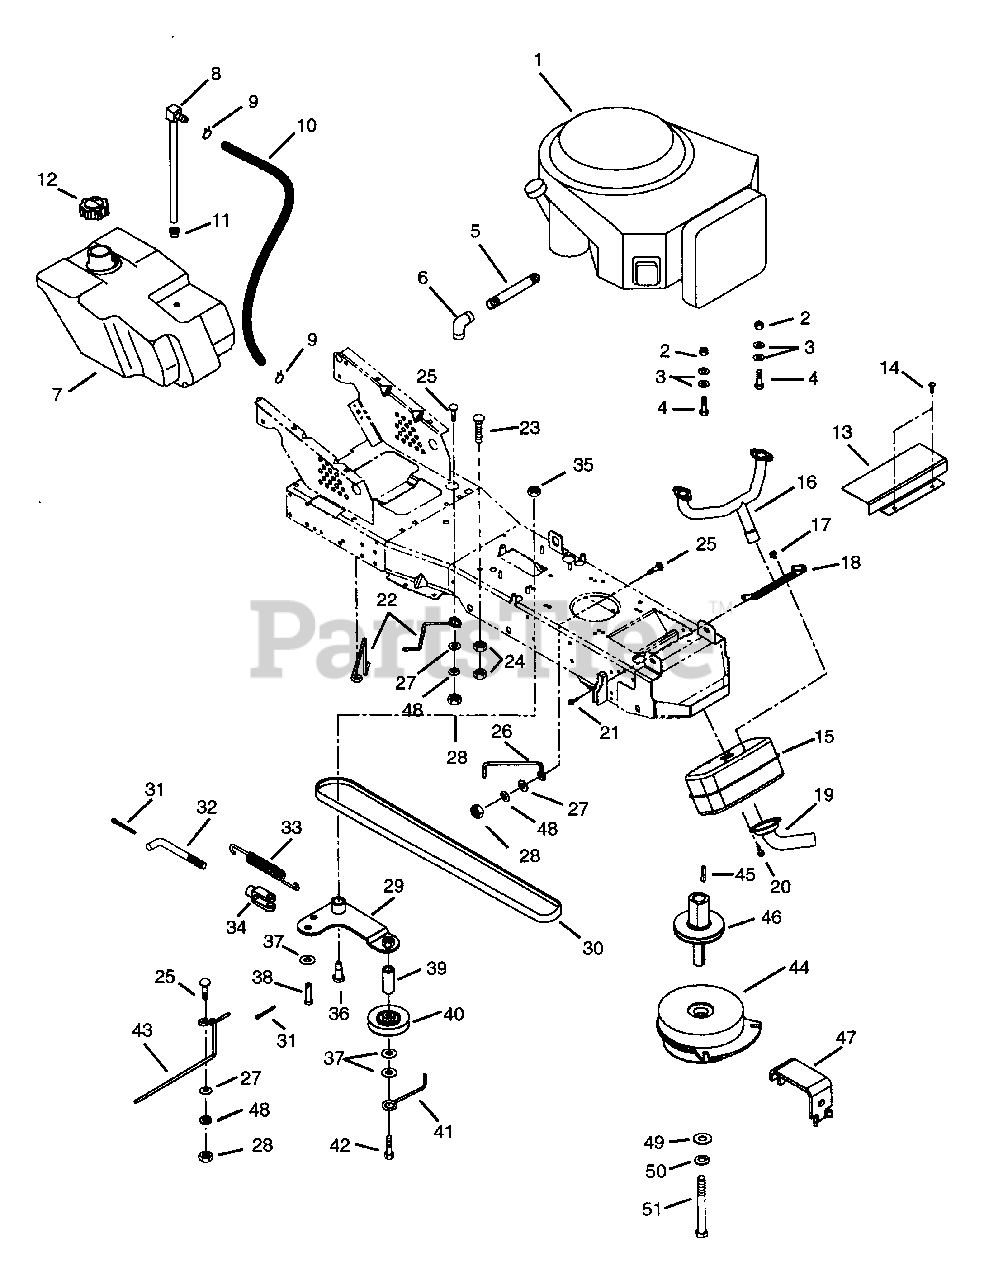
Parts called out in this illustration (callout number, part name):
1	18 HP B&S V-TWIN UT
2	NUT-LK-TOP .312-18 GR C PL
3	WSHR-FL-STL .328X.875X.062 PL
4	BLT-HEX .31-18X1.50 PL GR5
5	NIPPLE
6	ELBOW .375-18 NPTF
7	FUEL TANK
8	TANK FITTING
9	CLAMP-HOSE WIR.490/.510X.092#8
10	HOSE- FUEL LINE 48.00"
11	BSHG-FLG .375 X 1.062 X .625 R
12	FUEL CAP
13	SHIELD - HEAT
14	SCR-TAP .312-18X.50 PL F
15	MUFFLER - EXHAUST
16	PIPE - EXHAUST TWIN B&S
17	SCR-TAP 12-24X.50 HWH PL TR
18	BRACKET - MUFFLER
19	DEFLECTOR - EXHAUST
20	SCR-TAP 8-32X.38 SL HWH PL 23
21	SCR-TAP .312-18X.50 HWH PL TR
22	BELT FINGER
23	BLT-RDHDSQNK .31-18X1.25 SHTPL
24	NUT-LK .312-18 GR A PL
25	BLT-RDHDSQNK.31-18X.75GR5SHTPL
26	BELT FINGER
27	WSHR-FL-STL.344X.688X.065PL
28	NUT-HEX .312-18
29	IDLER PIVOT ARM
30	V-BELT, 3L-RAW EDGE
31	PIN-COTR .09X.75 PL
33	SG-TENS .091X.56X5.07 WLD 30
34	YOKE, .312-24 X 2.25
35	NUT-LK-CTR .375-16 GR A PL
36	BLT-SHLDR .38-16X1.25
37	WSHR-FL-STL .390X.750X.125 PL
38	PIN-CLEV .312X.822 HDND PL
39	TUBE .380 X .625 X 1.360
40	IDLER-V 3X.38
41	FINGER - BELT
42	BLT-HEX .38-16X1.75 PL GR2
43	BELT FINGER - CENTER
44	CLUTCH, ELECTRIC - WARNER
45	KEY-SQ .25 X 1.25 X .25 SAE
46	SHAFT, SHEAVE EXT.
47	ANCHOR- CLUTCH
48	WSHR-LK .312X.097 PL HVY
49	WSHR-FL-STL .463X1.375X.250 PL
50	WSHR-LK .438X.133 HVY
51	BLT-HEX .44-20X5.50 PL GR5
